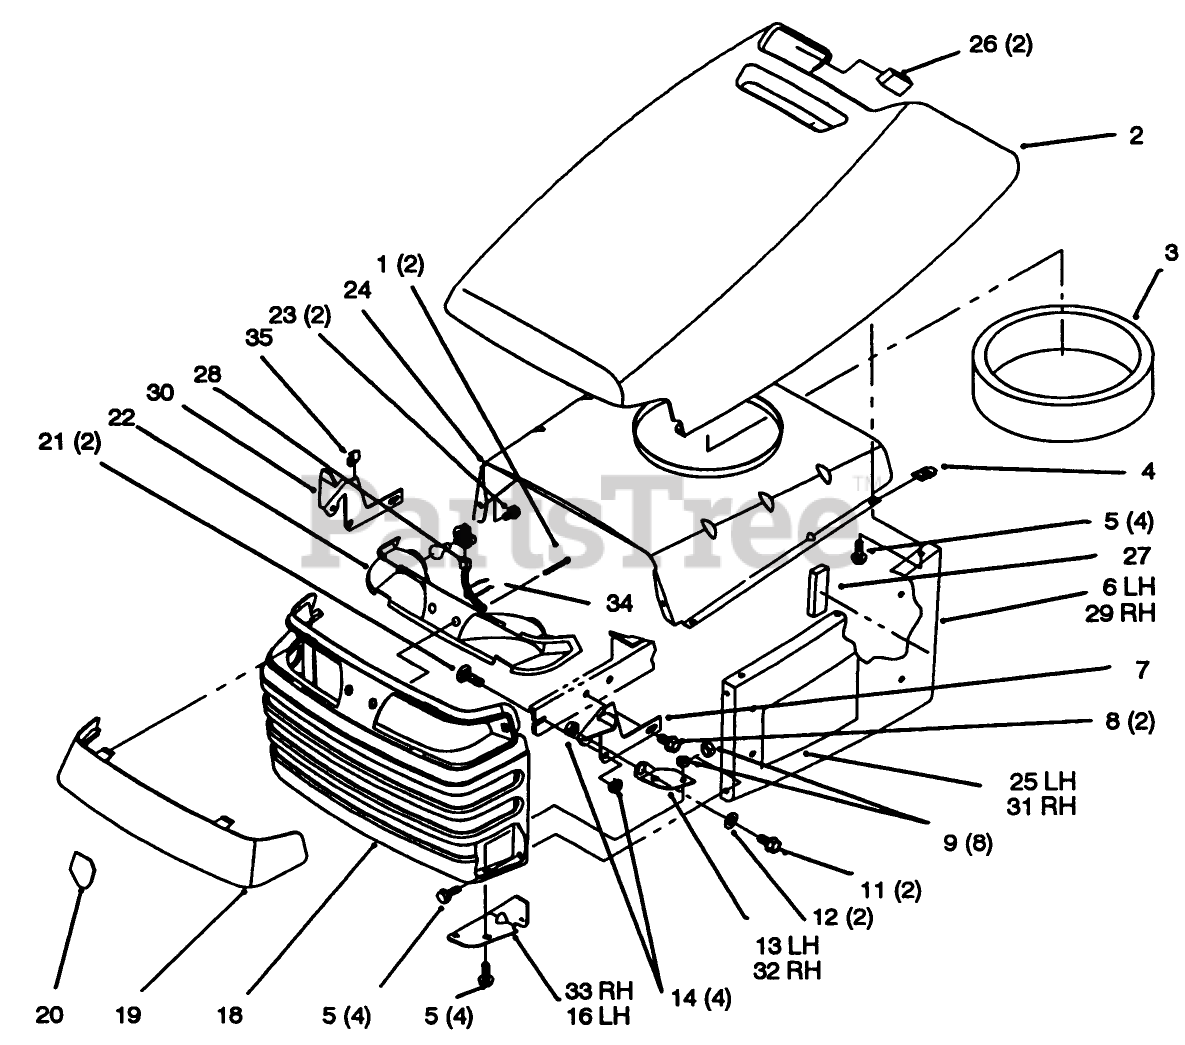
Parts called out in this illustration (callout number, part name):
3	SEAL-AIR INLET, TWIN
3	SEAL-AIR INLET
5	SCREW-HWH
6	HOOD-SIDE, LH
7	BRACKET-HINGE, LH
8	SCREW-HWHTF
9	NUT-LOCK, HHF
11	SCREW-HH
12	BUSHING
14	NUT-LOCK, NI
16	BRACKET-HOOD HINGE, RH
19	LENS - HEADLIGHT
21	BOLT-CARR
22	HEADLIGHT REFLECTOR ASM
23	SCREW-PLASTITE
24	BAFFLE-HOOD, UPPER
27	FOAM-SIDEPANEL
28	HARNESS-WIRE, LIGHTS
29	HOOD-SIDE, RH
30	BRACKET-HINGE, RH
31	DECAL - RH HOOD
32	HINGE-HOOD, RH
33	BRACKET-HOOD HINGE, LH
34	TIE-CABLE
35	CLIP-RETAINER, WIRE
